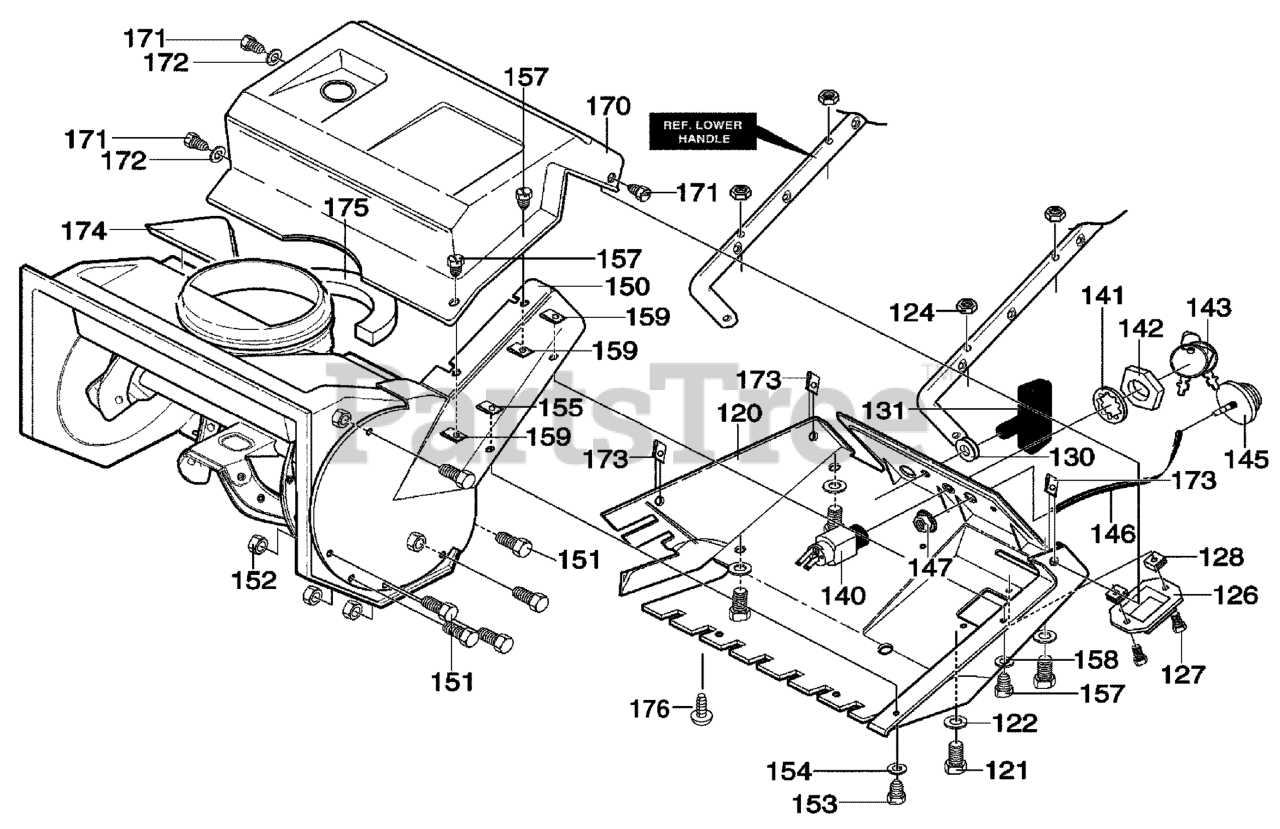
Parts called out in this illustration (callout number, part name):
120	COVER, BOTTOM
121	SCREW, 1/4-20X1.25
122	WASHER, FLAT .281X.63X.065
124	NUT, 1/4-20 YZ
126	COVER, CARB
127	SCREW, 1/4-14X.75
128	NUT, 1/4-10 SPEED J TYPE
130	GROMMET & WASHER, ROPE GUIDE
131	KNOB, STAND TEE
140	SWITCH, IGNITION
141	WASHER
142	NUT, 5/8-32 ACC
143	2 KEYS & RING
145	PRIMER, ENGINE
146	HOSE, PRIMER
147	KEPS NUT, 1/4-20
150	COVER, BELT
151	SCREW, 10-24X.50
152	NUT, #10-24
153	SCREW, 1/4-20X.50
154	WASHER, FLAT .281X.63X.065
155	NUT, 1/4-20 TINN
157	SCREW, 1/4-14X.75
158	WASHER, FLAT .281X.63X.065
159	NUT, 1/4-20 SPEED J TYPE
170	COVER, TOP
171	SCREW, 1/4-14X.75
172	WASHER, FLAT .281X.63X.065
173	NUT, 1/4-10 SPEED J TYPE
174	SEAL, FOAM
175	SEAL, STRIP CHUTE & GAS SEAL
176	SCREW 10-14 x 0.63
